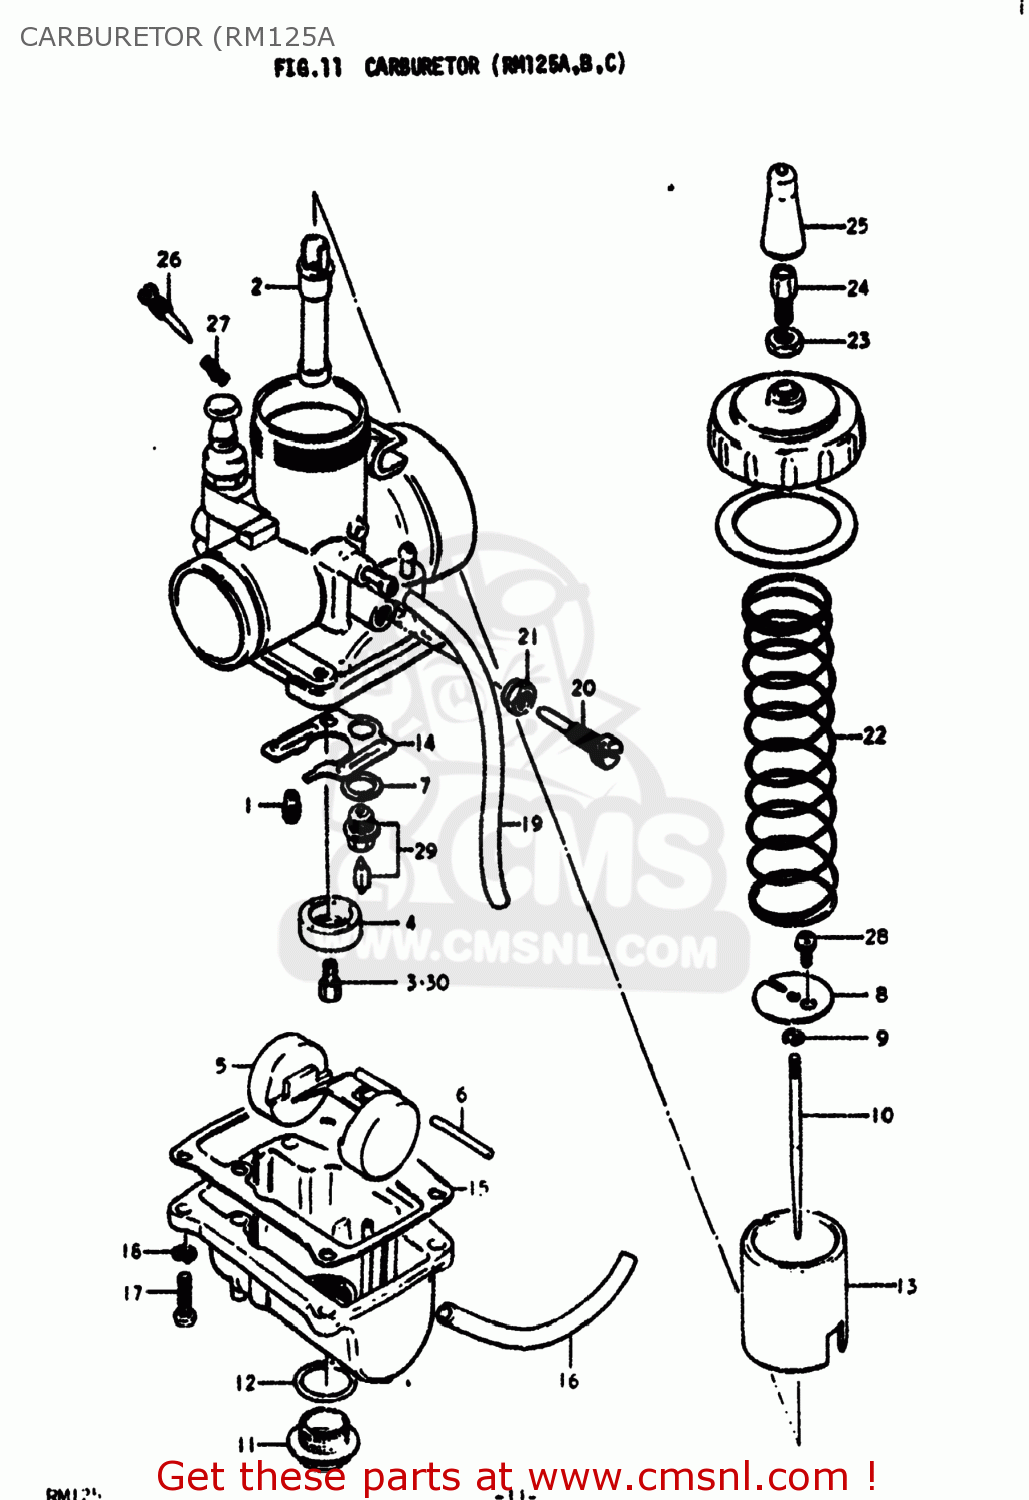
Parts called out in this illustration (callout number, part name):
0	CARBURETOR ASSEMBLY
1	JET
2	JET,NEEDLE
3	JET
4	RING
5	FLOAT
6	PIN,FLOAT
7	GASKET,MAIN JET HOLDER (NAS)
8	CLIP
9	CLIP
10	NEEDLE, JET (6DP5-3)
11	SCREW,GUIDE
12	O RING,DRAIN PLUG
13	VALVE,THROTTLE
14	PLATE
15	GASKET,FLOAT CAHMBER (NAS)
16	HOSE
17	SCREW
18	LOCK WASHER
19	HOSE
20	ADJUSTER
21	NUT
22	SPRING
23	NUT
24	ADJUSTER,CABLE
25	CAP
26	SCREW,PILOT AIR
27	SPRING
28	SCREW
29	VALVE ASSY,NEEDLE
30	JET
